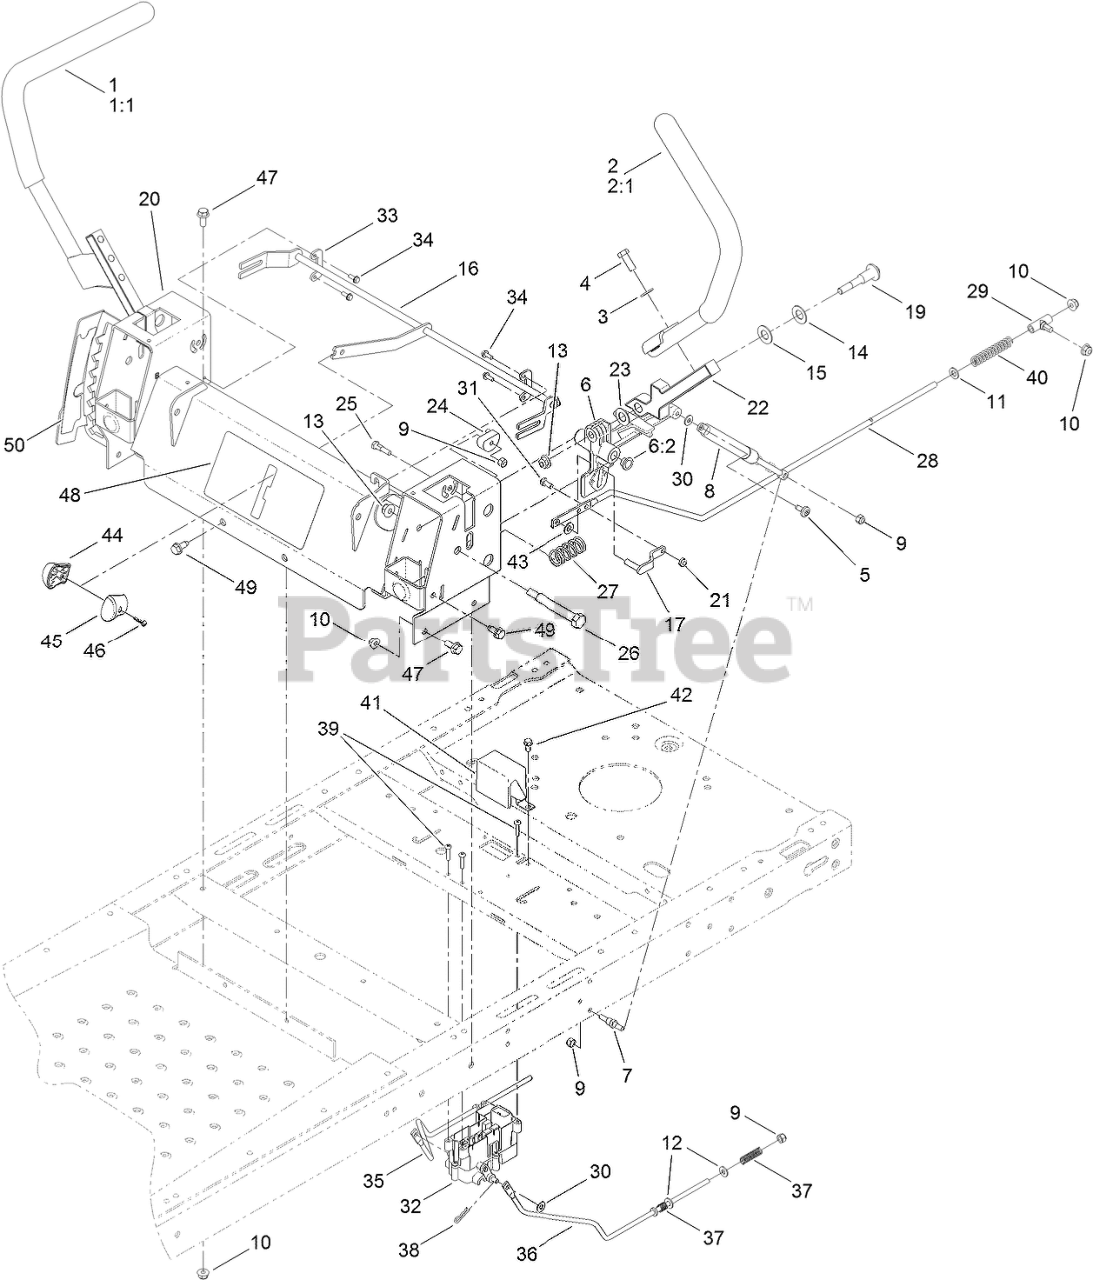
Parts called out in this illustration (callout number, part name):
1	RH HANDLE ASM
2	LH HANDLE ASM
3	WASHER-FLAT
4	SCREW-HH
5	SCREW-SHOULDER
6	ACTUATOR ARM ASM
6:2	BUSHING-FLANGE
7	STUD-DAMPER
8	Damper-Control, Motion
9	NUT-LOCK, NI
10	NUT-HF, NI
11	WASHER-PLAIN
12	WASHER-FLAT
13	NUT-HF, NI
14	WASHER-BELLEVILLE
15	WASHER
16	CONTROL-SPEED
17	PIN-ROD, HYDRO
19	BOLT-PIVOT
20	BOX-CONTROL
21	NUT-LOCK, NI
22	LEVER-CONTROL
23	WASHER-NYLON
24	ECCENTRIC
25	BOLT-PIVOT, ECCENTRIC
26	BOLT-PIVOT
27	SPRING-RETURN
28	ROD-HYDRO
29	MOUNT-ROD, HYDRO
30	WASHER
31	SCREW-HH
32	BRAKE CONTROL MODULE ASM
33	RETAINER
34	SCREW-TAPTITE
35	ROD-BRAKE, RH
36	ROD-BRAKE, LH
37	SPRING-COMPRESSION
38	PIN-COTTER
39	SCREW-PPH
40	SPRING-RETURN, NEUTRAL
41	COVER-BRAKE
42	SCREW-HWH
43	SPACER-NYLON
44	KNOB-RH
45	KNOB-LH
46	SCREW-PPH
47	SCREW-HHF
48	DECAL-SPEED CONTROL
49	SCREW-HWHTF
50	DECAL-HOC
